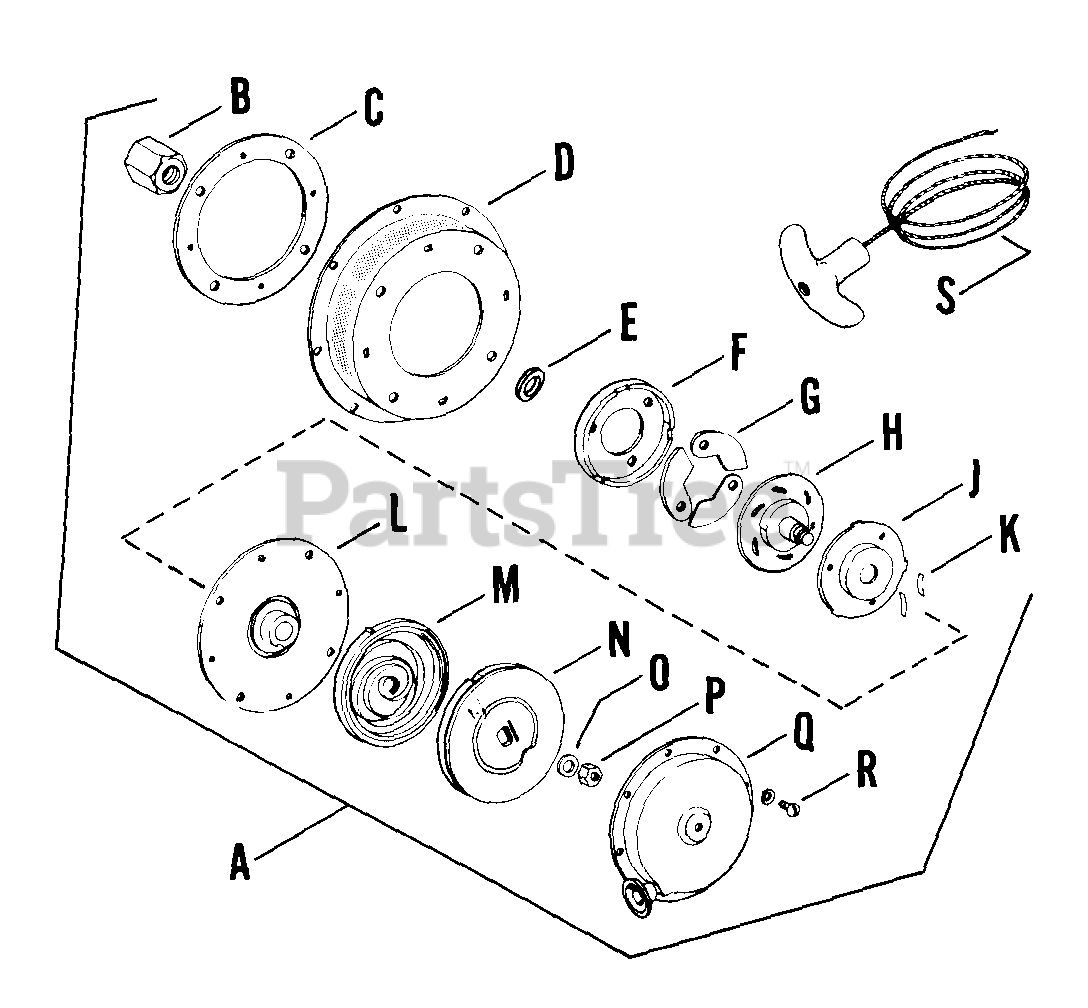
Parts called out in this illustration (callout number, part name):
L	Plate, mounting & bushing
M	SPRING - DISCONTINUED
P	Nut, hex. 5/16 - 24
R	SCREW - DISCONTINUED
S	Cable, w/handle 48 (steel)
